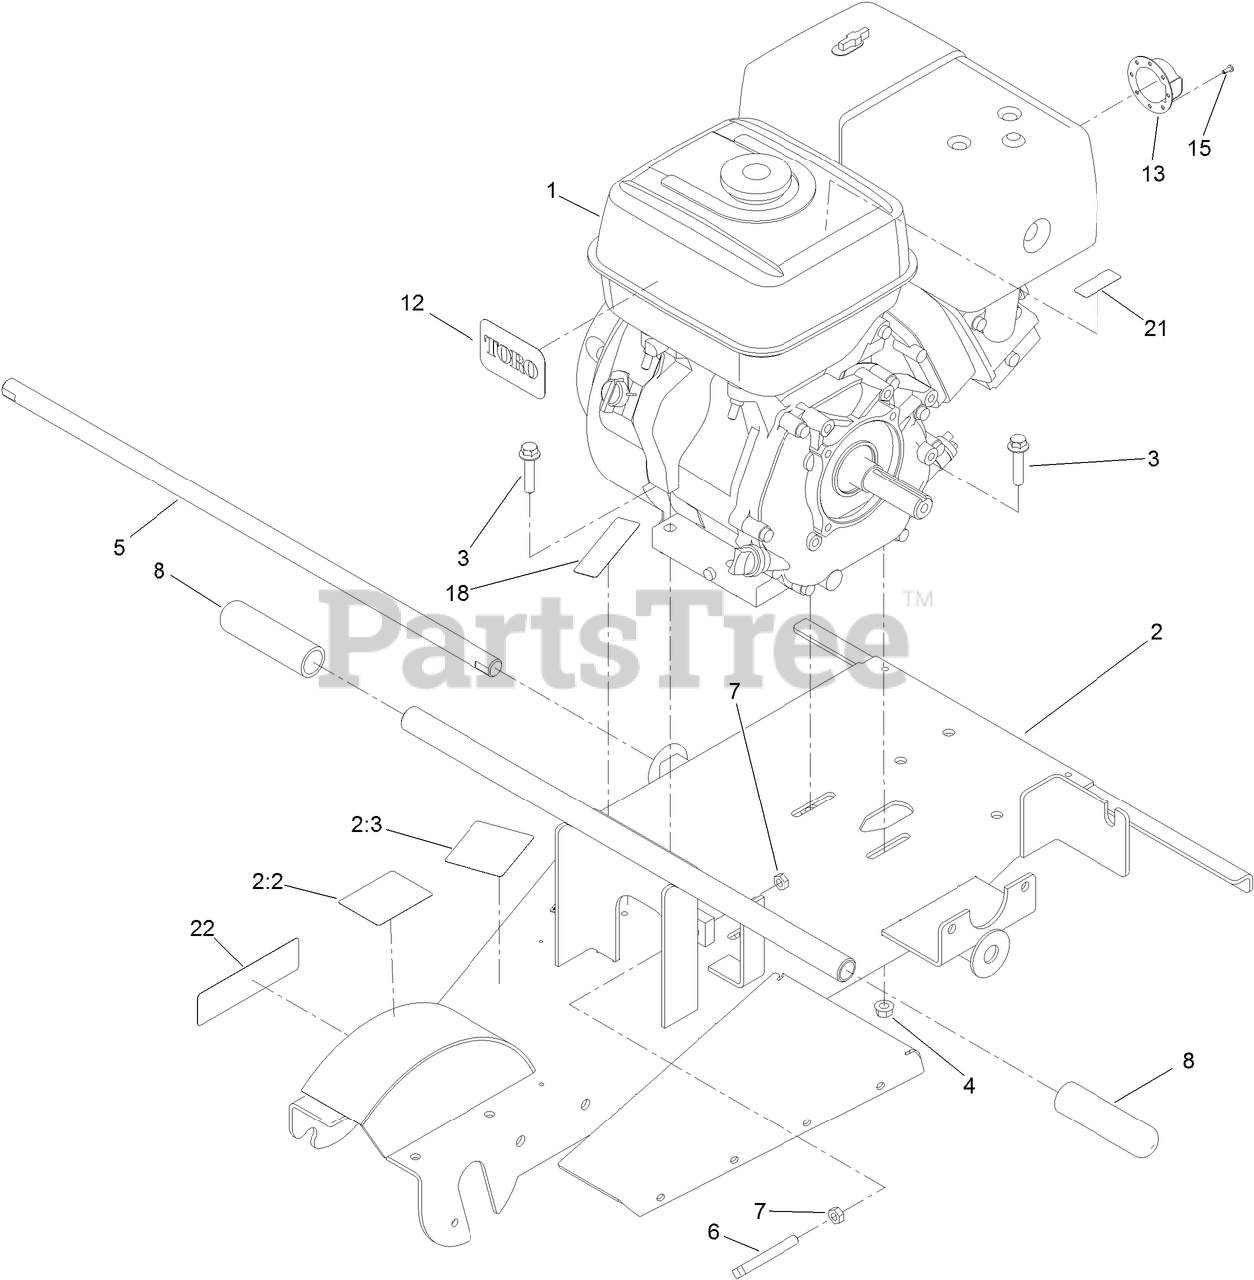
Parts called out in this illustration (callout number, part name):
2	FRAME ASM
2:2	DECAL-DANGER
2:3	DECAL-CAUTION
3	SCREW-HHF
4	NUT-HF
5	BAR-AXLE
6	SCREW-SET, SQH
7	NUT-HEX
8	GRIP-HANDLE
12	DECAL
13	DEFLECTOR-EXHAUST
15	SCREW-SELF TAPPING
18	DECAL-ARRESTER, SPARK
21	DECAL-WARNING, ETHANOL
22	DECAL-ROTATE TOOTH
